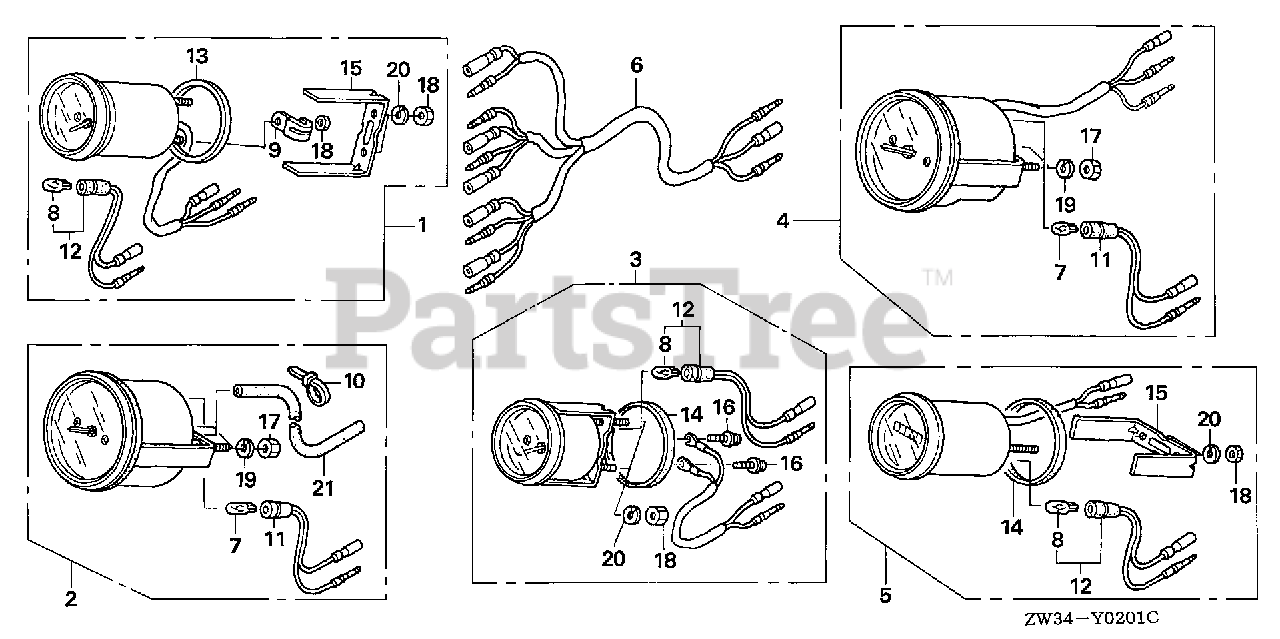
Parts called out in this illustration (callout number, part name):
1	METER KIT, TRIM
1	METER KIT, TRIM *NHA85* (B) (BLACK)
4	METER KIT, TACHO (NOT AVAILABLE)
4	METER KIT, TACHO *NHA85* (B) (BLACK)
7	BULB, WEDGE BASE (T10) (12V 1.7W) (STANLEY)
8	BULB, WEDGE BASE (12V 1.7W)
9	CLAMP
11	SOCKET
12	SOCKET
13	GASKET
15	BRACKET
17	NUT, HEX. (5MM)
18	NUT, HEX. (4MM)
19	WASHER, SPRING (5MM)
20	WASHER, SPRING (4MM)
